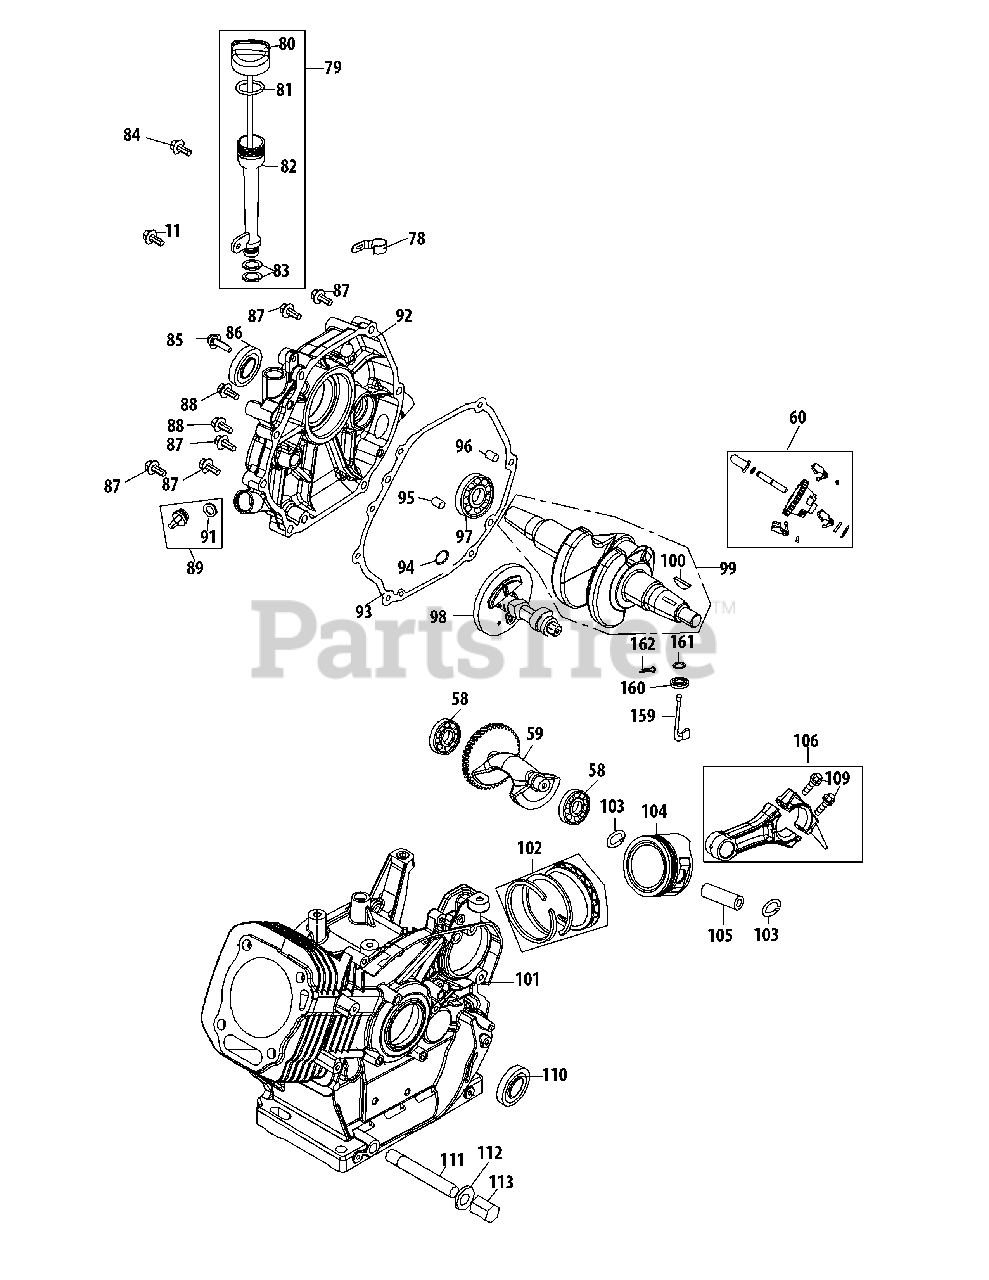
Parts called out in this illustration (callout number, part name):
58	RADIAL BALL BEARING, 6202-P6
59	BALANCEABLE SHAFT ASSY.
60	GOVERNOR GEAR
78	DIPSTICK CLAMP
79	DIPSTICK ASSEMBLY
80	DIPSTICK
81	DIPSTICK O-RING
82	OIL FILL TUBE
83	OIL FILL TUBE O-RING
84	BOLT M6×8
85	BOLT M8×45
86	OIL SEAL, 35×52×7
87	BOLT M8×38
88	BOLT M8×35
89	OIL FILLER PLUG COMP
91	O-RING 16×3
92	CRANKCASE COVER
93	CRANKCASE COVER GASKET
94	WASHER 16×24×0.5
95	DOWEL PIN 9×12
96	DOWEL PIN 7×14
97	BEARING, 6207-P6
98	CAMSHAFT ASSEMBLY
99	CRANKSHAFT ASSEMBLY
100	WOODRUFF KEY
101	CRANKCASE COMP.
102	PISTON RING SET
103	PISTON PIN SNAP RING
104	PISTON
105	PISTON PIN
106	CONNECTING ROD ASSEMBLY
109	CONNECTING ROD BOLT
110	OIL SEAL 35×52×7
111	OIL DRAIN PIPE
112	WASHER 10×16×1.5
113	OIL DRAIN PLUG
159	GOVERNOR ARM SHAFT
160	GOVERNOR SEAL
161	WASHER 8×20×0.8
162	COTTER PIN
